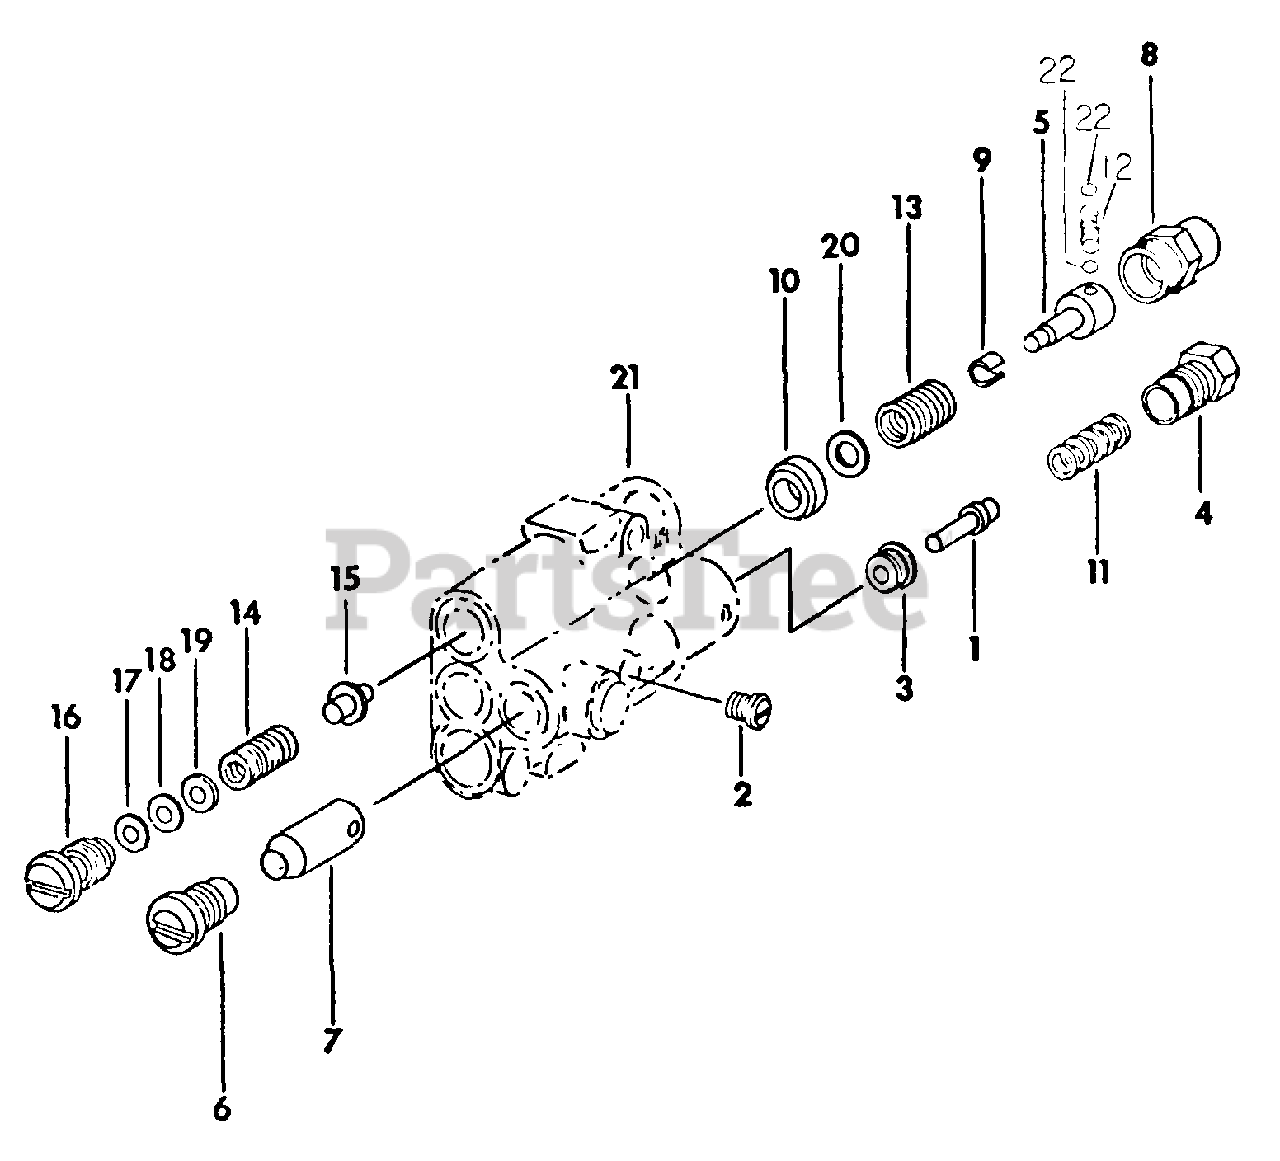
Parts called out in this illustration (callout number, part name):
3	SEAT, WASHER
4	PLUG, ADAPTER
5	SCREW, DETENT
6	PLUG, PLUNGER
10	BUSHING, DETENT
11	SPRING, LOCKOUT
12	SPRING, DETENT
13	SPRING, SPOOL CENTERING
14	SPRING, POPPET
15	POPPET
16	PLUG, POPPET
17	WASHER, .015
18	WASHER, .010
19	WASHER, .035
20	WASHER, .046
21	BODY
22	BALL, 5/32 CR-STL
